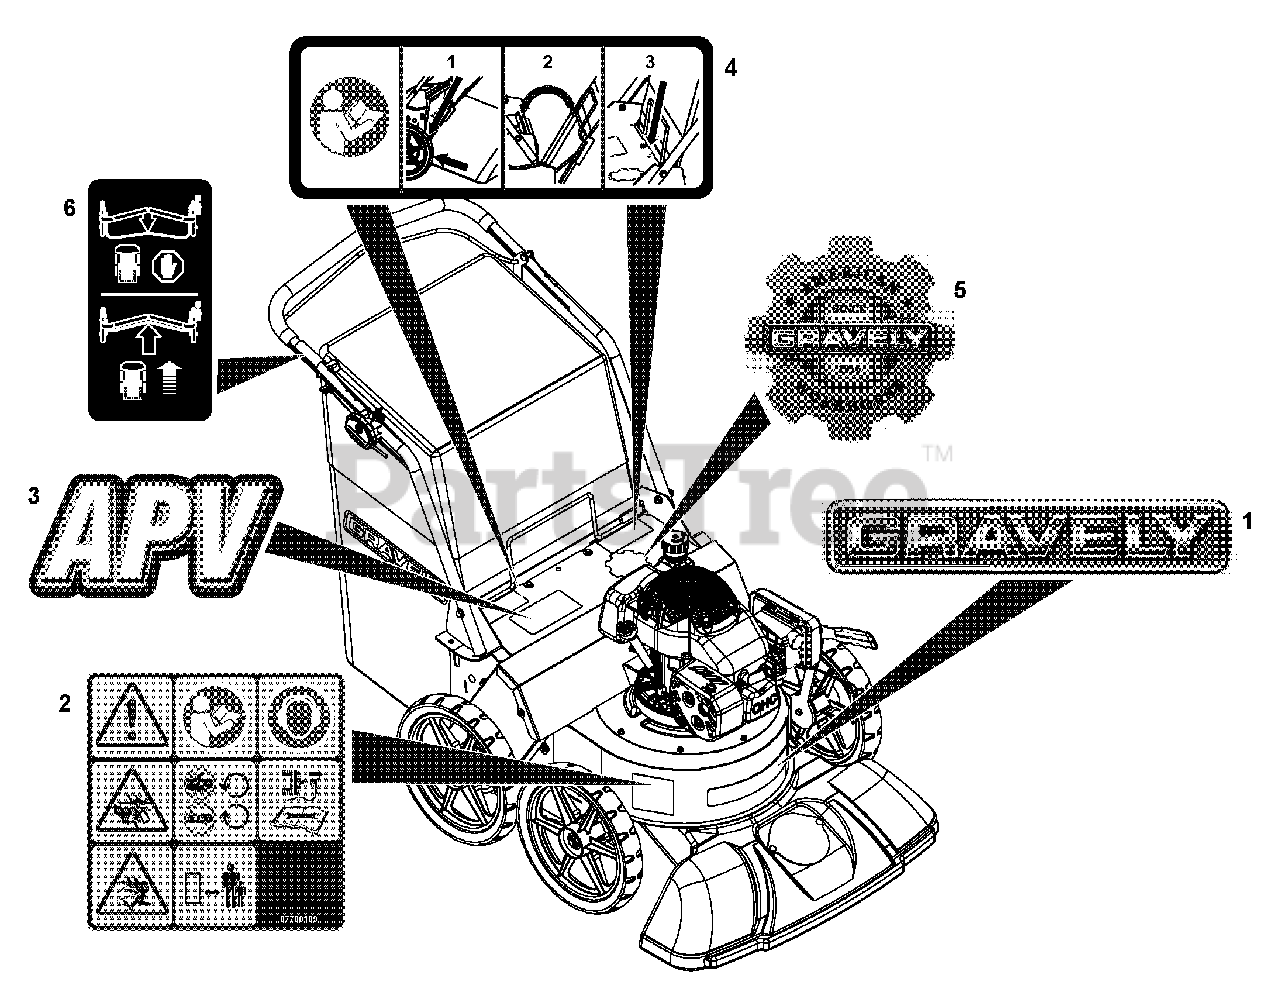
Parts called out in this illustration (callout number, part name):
1	DECAL, 9.5" GRAVELY LOGO
2	DECAL, WARNING - VAC ISO CE
3	DECAL, ACCESS APV
4	DECAL, BAG INSTRUCTIONAL - APV
5	DECAL, GRAVELY HERITAGE - LARGE
6	DECAL, DRIVE CONTROL - APV
